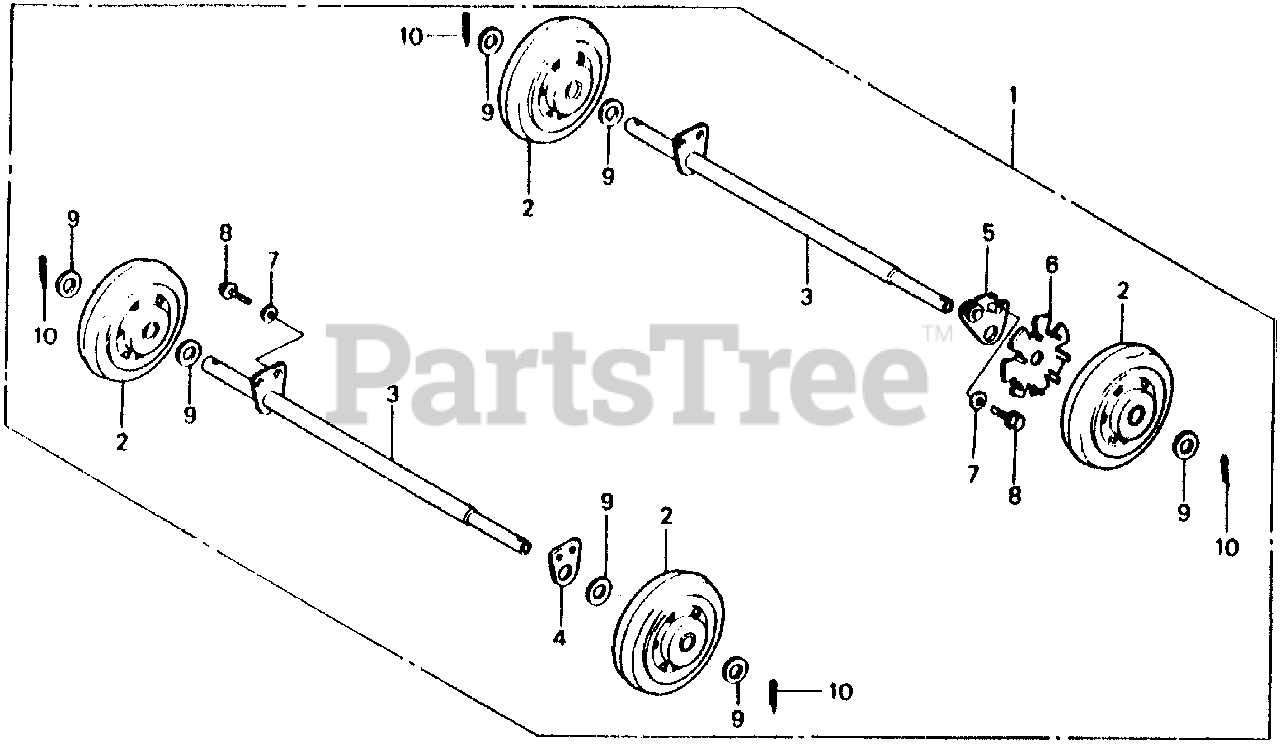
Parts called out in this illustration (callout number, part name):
2	WHEEL
3	SHAFT, WHEEL
4	PLATE, SETTING
5	STAY, STOPPER
6	PLATE, LOCK
7	WASHER (8MM)
8	BOLT-WASHER (8X25)
9	WASHER, FLAT (20MM)
10	PIN, COTTER (4.0X30)
